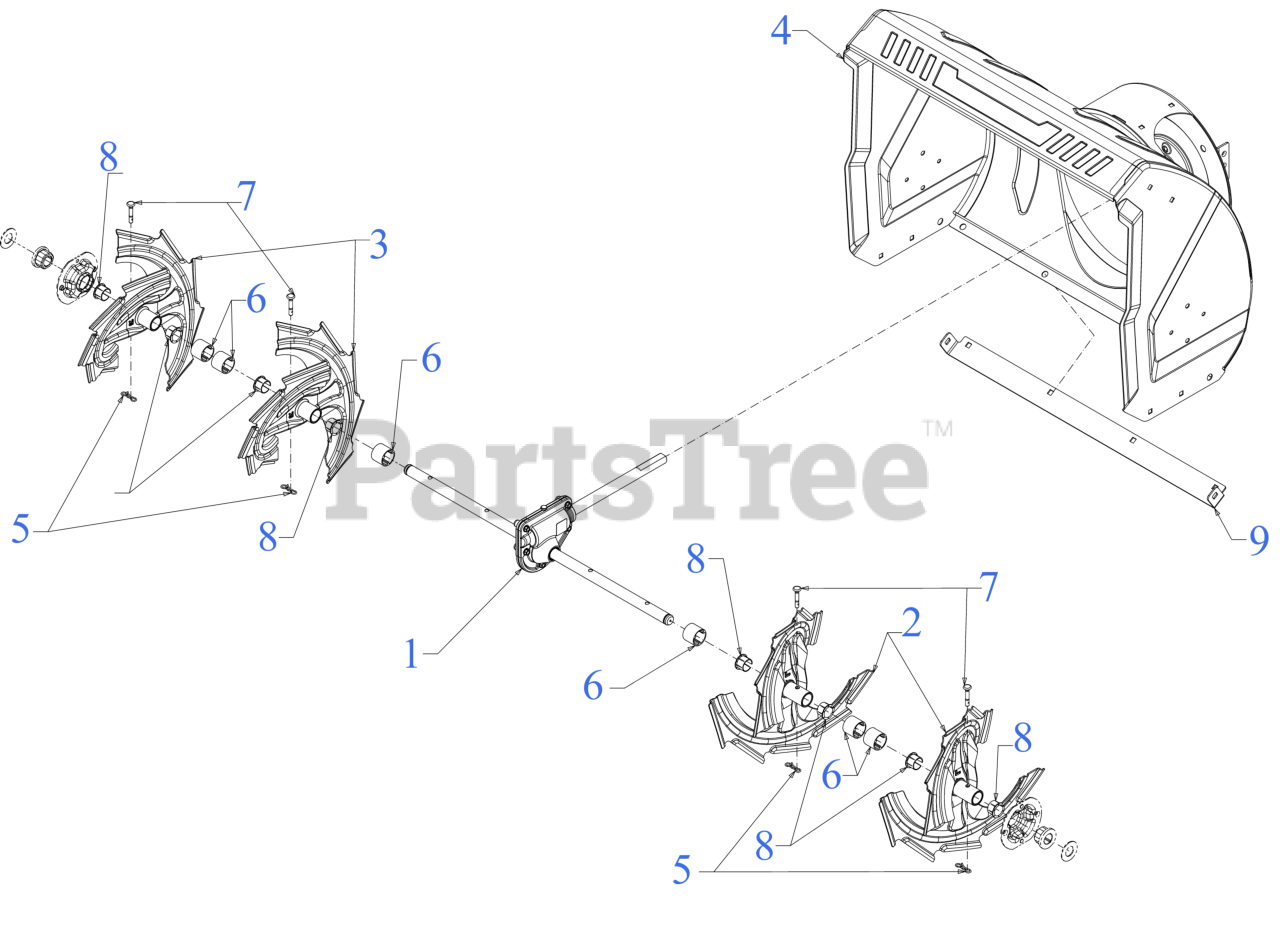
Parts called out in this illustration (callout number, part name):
1	GEARBOX ASSEMBLY 26"
2	10T AUGER SPIRAL (LH)
3	10T AUGER SPIRAL (RH)
4	26" AUGER HOUSING
5	BOW TIE COTTER PIN 1/4-5/16
6	SPACER 1.25OD x .75ID X1.00 LG
7	SHEAR PIN .25 x 1.50 GR2
7	Troy-Bilt SHEAR PIN 6PK (04124A)
7	Cub Cadet SHEAR PINS (2X SNOW)
7	SHEAR PINS QTY 4
8	FLANGE BUSHING
9	26" SHAVE PLATE
